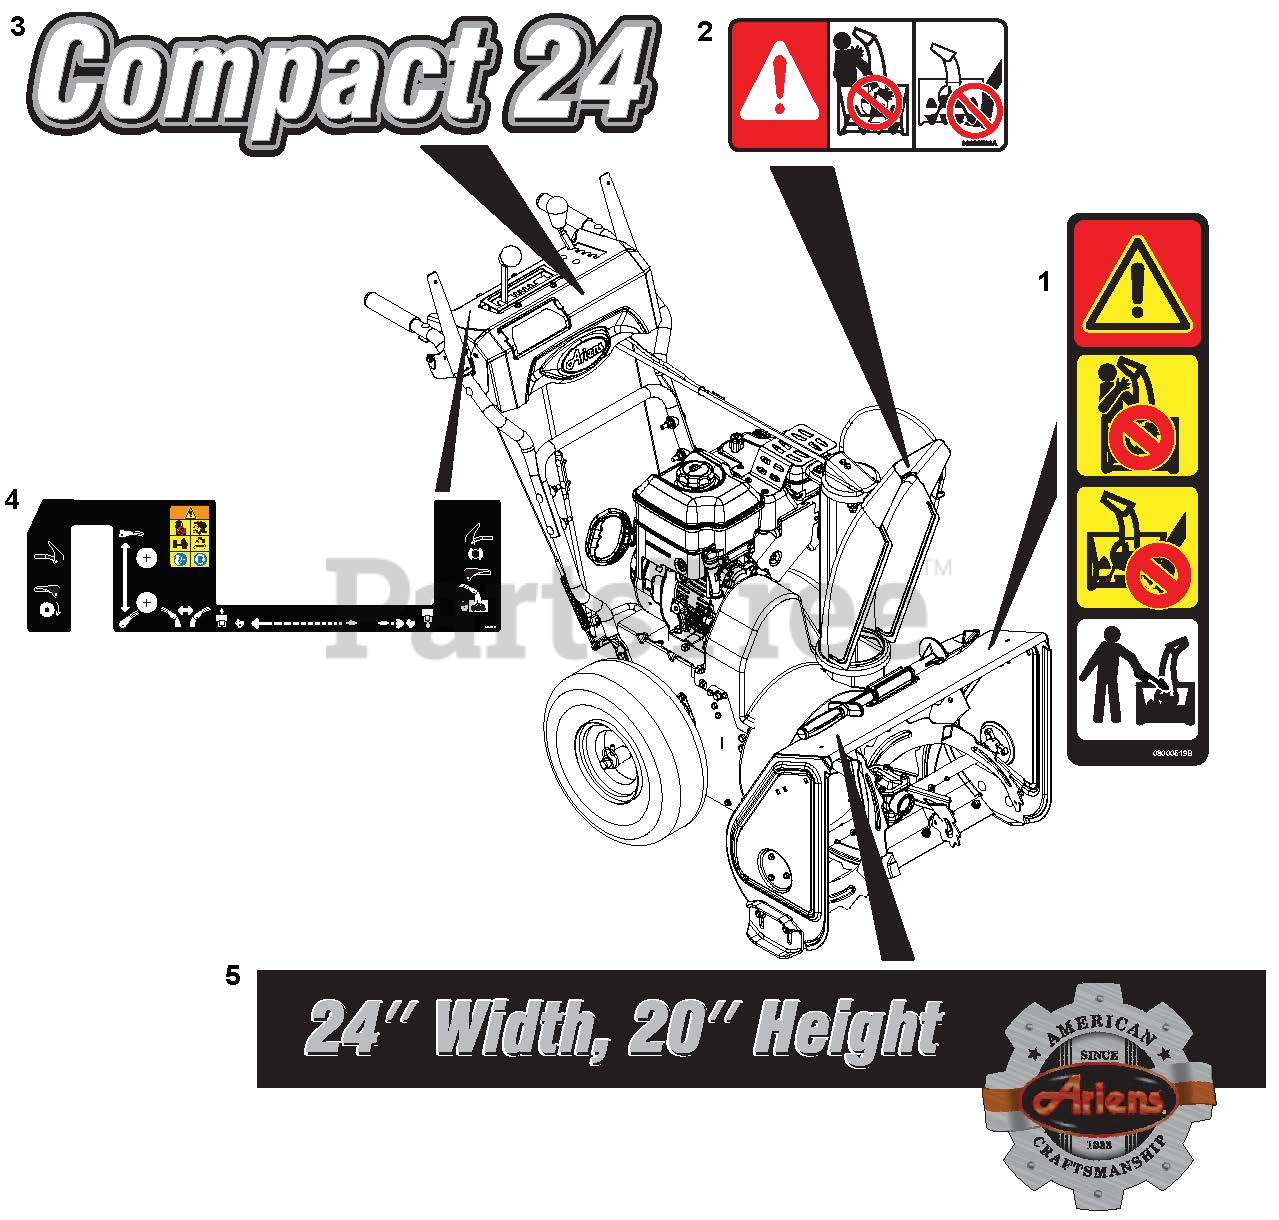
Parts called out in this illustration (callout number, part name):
1	DECAL, DANGER - ROTATING PARTS
2	DECAL, DANGER
3	DECAL, ST20 COMPACT
3	DECAL, COMPACT 22
3	DECAL, COMPACT 24
4	DECAL,CONTROL - COMPACT MANUAL
4	DECAL,CONTROL - COMPACT REMOTE
4	DECAL, CONTROL-COMPACT TRACK
5	Decal, Ariens Heritage
